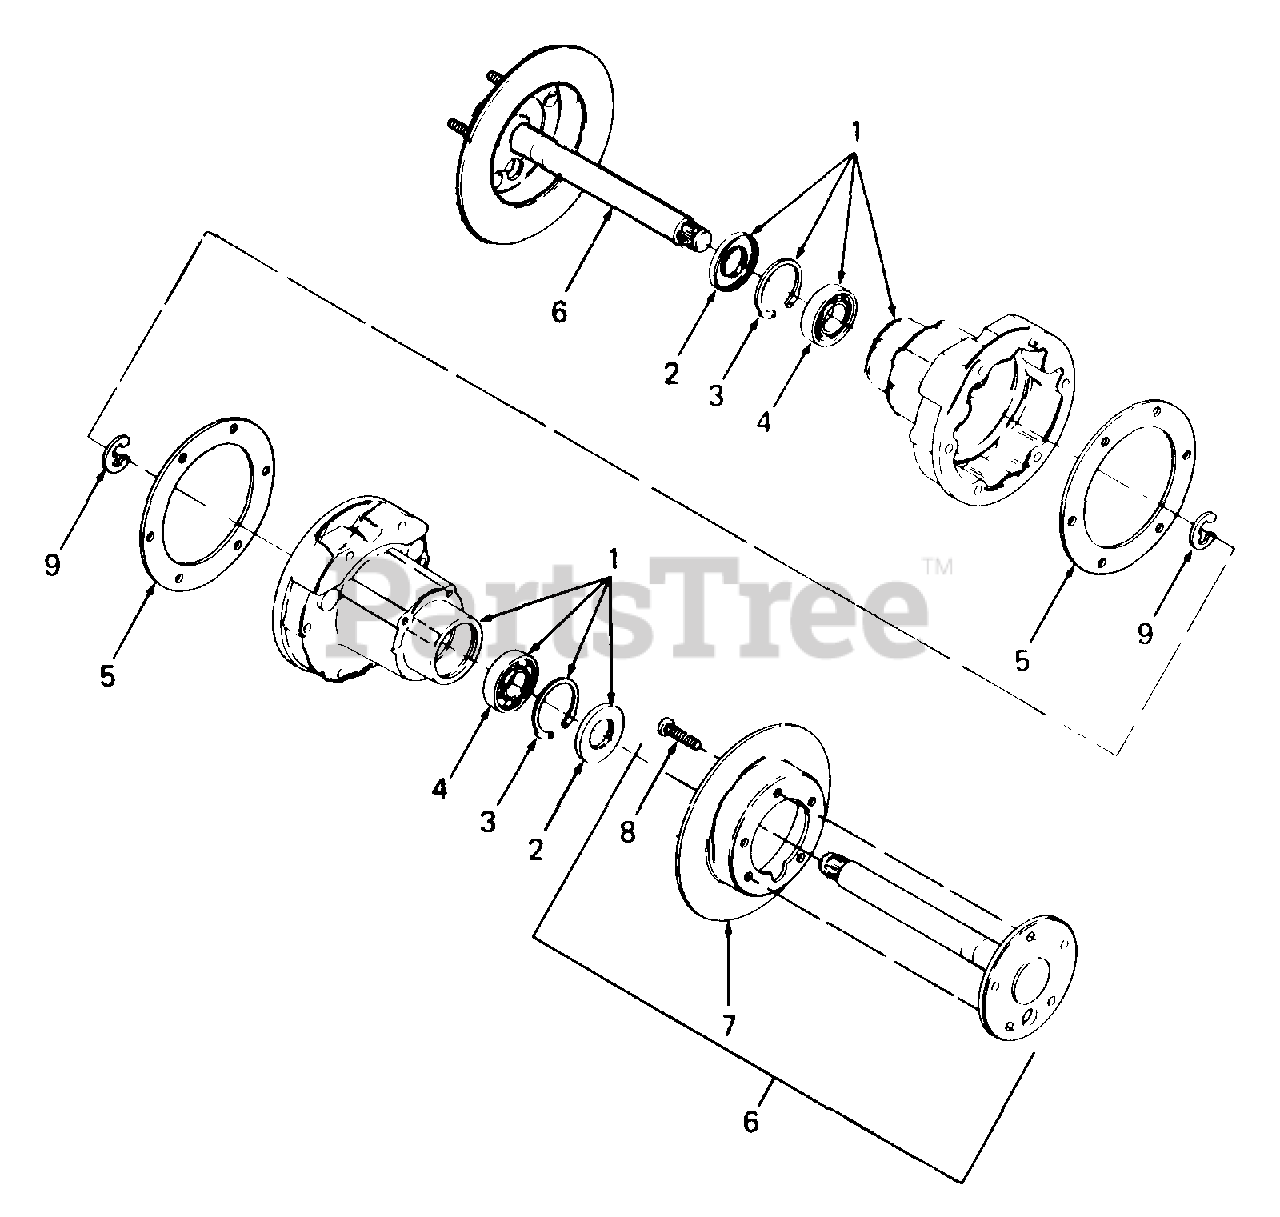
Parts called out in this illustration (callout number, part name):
1	Carrier Assy, Rear Axle
2	Seal, Oil
3	Ring, Retaining
4	Bearing, Ball
5	Gasket, Carrier
6	Axle Assy, Rear
7	Disc, Brake
8	Bolt, Lug
9	Retainer, E-Ring
